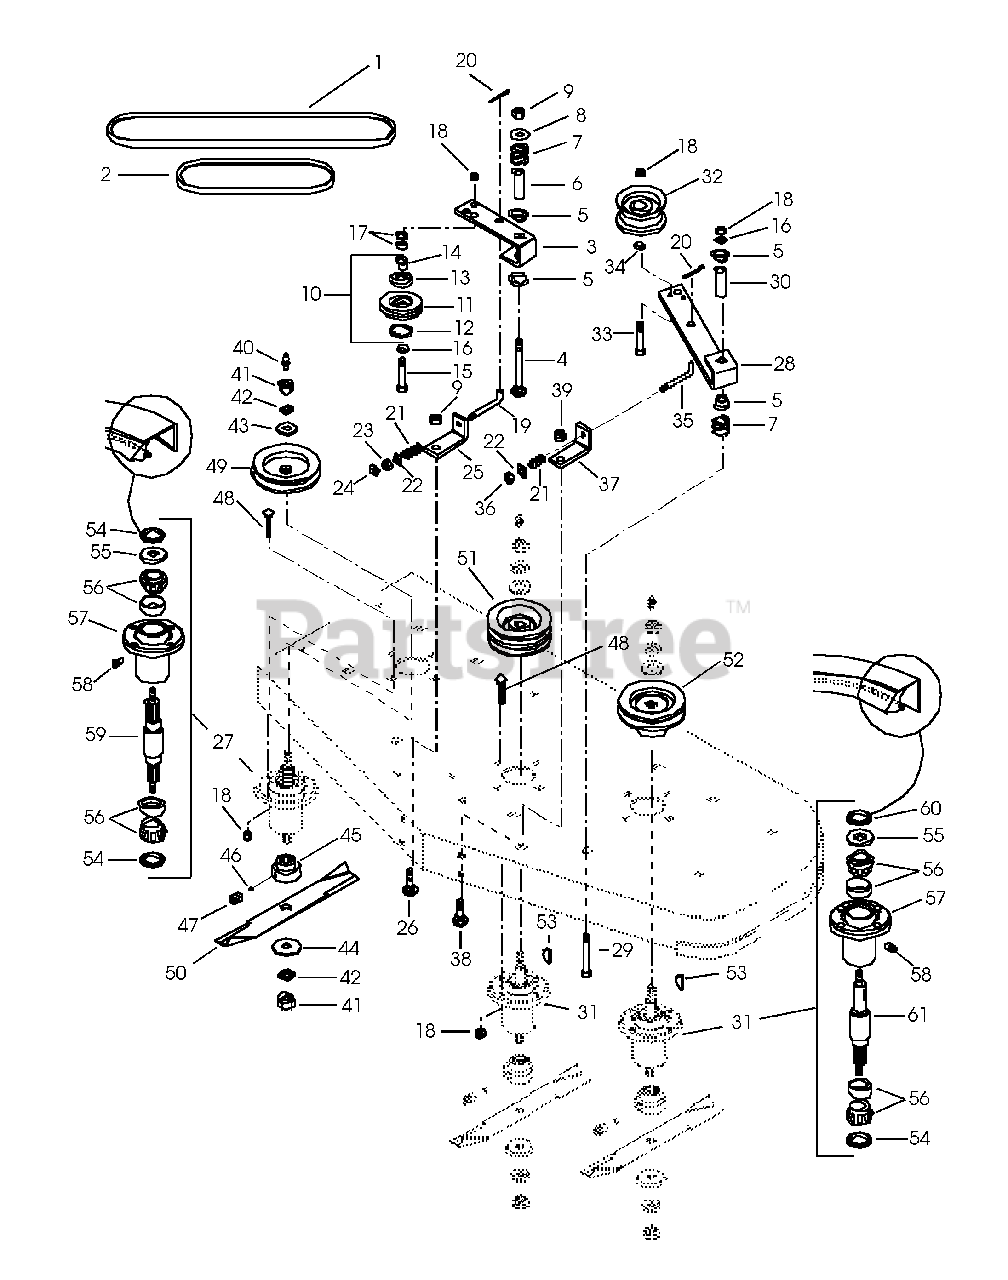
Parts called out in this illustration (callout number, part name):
1	V-Belt A-Section 50.25 x .561/.031
2	V-Belt A-Section 18.05 x .495
3	Arm-Idler Pivot
4	Bolt-Hex .50-13 x 6.50 Grade 5
5	Bushing-Flange .762 x 1.0 x .580 x 1.48
6	Spacer .560 x .750 x 2.437
7	Spring-Compression .085 x .80 x 1.00
8	Washer-Flat-Steel .563 x 1.38 x .109
9	Nut-Locking .50-13
10	Assembly-Idler Sheave
11	Sheave-Idler
12	Ring-Retaining-Internal 2.054 x .062
13	Bearing-Ball 1.85 x .787 x .55
14	Bushing-Flange .786 x 1.0 x .79
15	Bolt-Hex .38-16 x 2.00 Grade 5
16	Washer-Flat-Steel .438 x 1.00 x .083
17	Bushing .406 x .750 x .188
18	Nut-Locking-Center .375-16
19	Rod-Idler
20	Pin-Cotter .09 x .75
21	Spring-Compression .125 x .78 x 1.00
22	Washer-Flat-Steel .281 x .625 x .065
23	Nut-Hex .375-16
24	Nut-Hex-Jam .375-16
25	Bracket-Belt Tensioner
26	Bolt-Round Head Square Neck .50-13 x 1.50
27	Service Kit
28	Weldment-Ground Drive Idler
29	Bolt-Hex .38-16 x 3.50 Grade 5
30	Bushing-Steel .437 x .750 x 2.44
31	Service Kit
32	Idler-Flat 4-.687 x .38
33	Bolt-Hex .38-16 x 2.25 Grade 5
34	Bushing-Flange .406 x .88 x .270 x .140
35	Rod-Idler 50 In. Mower
36	Nut-Locking-Nylon w/insert .375-24
37	Bracket
38	Bolt-Round Head Square Neck .31-18 x 1.0
39	Nut-Locking-Nylon .312-18
40	Fitting-Lube 1/8
41	Nut-Hex .625-11
42	Washer-Locking .625 x .156
43	Washer-Flat-Steel .97 x 1.865 x .063
44	Washer
47	Screw-Set .25-20 x .25
48	Bolt-Round Head Square Neck .38-16 x 1.375
49	Sheave
50	Blade-50 Inch Mower
51	Sheave
52	Sheave
53	Key-Woodruff .25 x 1
54	Seal 1.987 x 1.375 x .313
55	Washer-Flat-Steel 1.007 x 1.542 x .062
56	Assembly-Bearing Cup & Cone
57	Housing-Bearing
58	Relief Fitting - Grease
59	Shaft-Spindle
60	Seal 1.987 x 1.500 x .313
61	Shaft-Spindle
